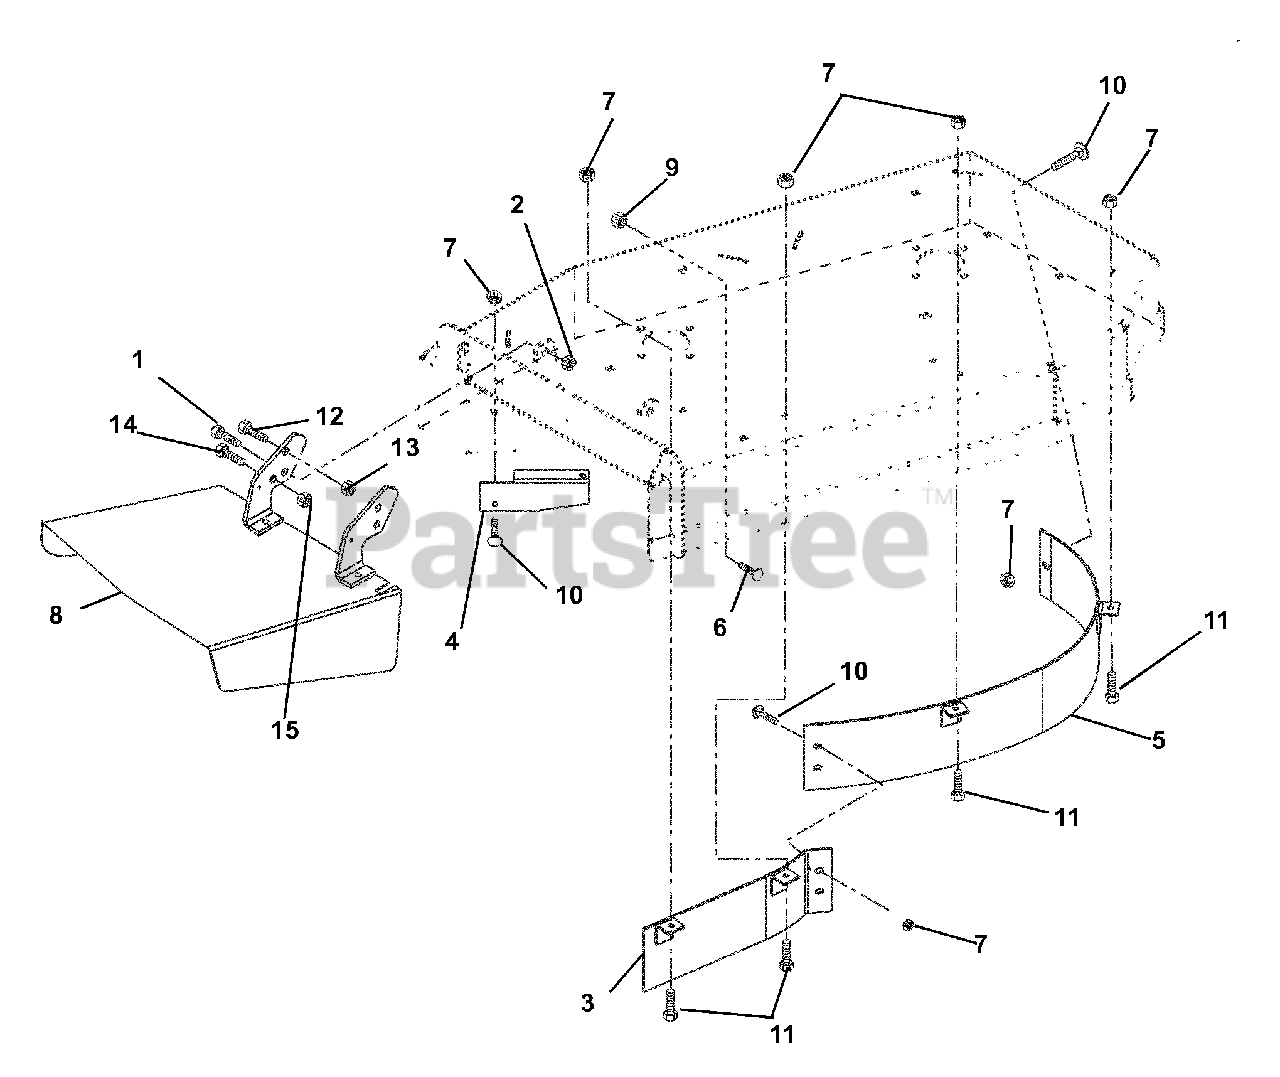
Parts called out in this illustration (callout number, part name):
1	@BLT-HEX .50-13X1.25 GR5 YWZC
2	@NUT-LK-NYL .50-13 YWZC
3	BAFFLE - RIGHT FRONT - 32"
4	DEFLECTOR - 32"
5	BAFFLE - LEFT FRONT - 32"
6	@BLT-RDHDSQNK .38-16X1.00 G5YZ
7	@NUT-LK-TOP-FLG .31-18 YWZC
8	WMT - DISCHARGE CHUTE - PRO
9	@NUT-LK-TOP-FLG .38-16 YWZC
10	@BLT-RDHDSQNK .31-18X.75 G5YZ
11	@BLT-HEX .31-18X.75 GR5 YWZC
12	@BLT-HEX .38-16X.75 GR5 YWZC
13	@NUT-LK-CTR .38-16 YWZC
14	@BLT-HEX .25-20X.75 GR5 YWZC
15	@NUT-LK-NYL .250-20 YWZC
